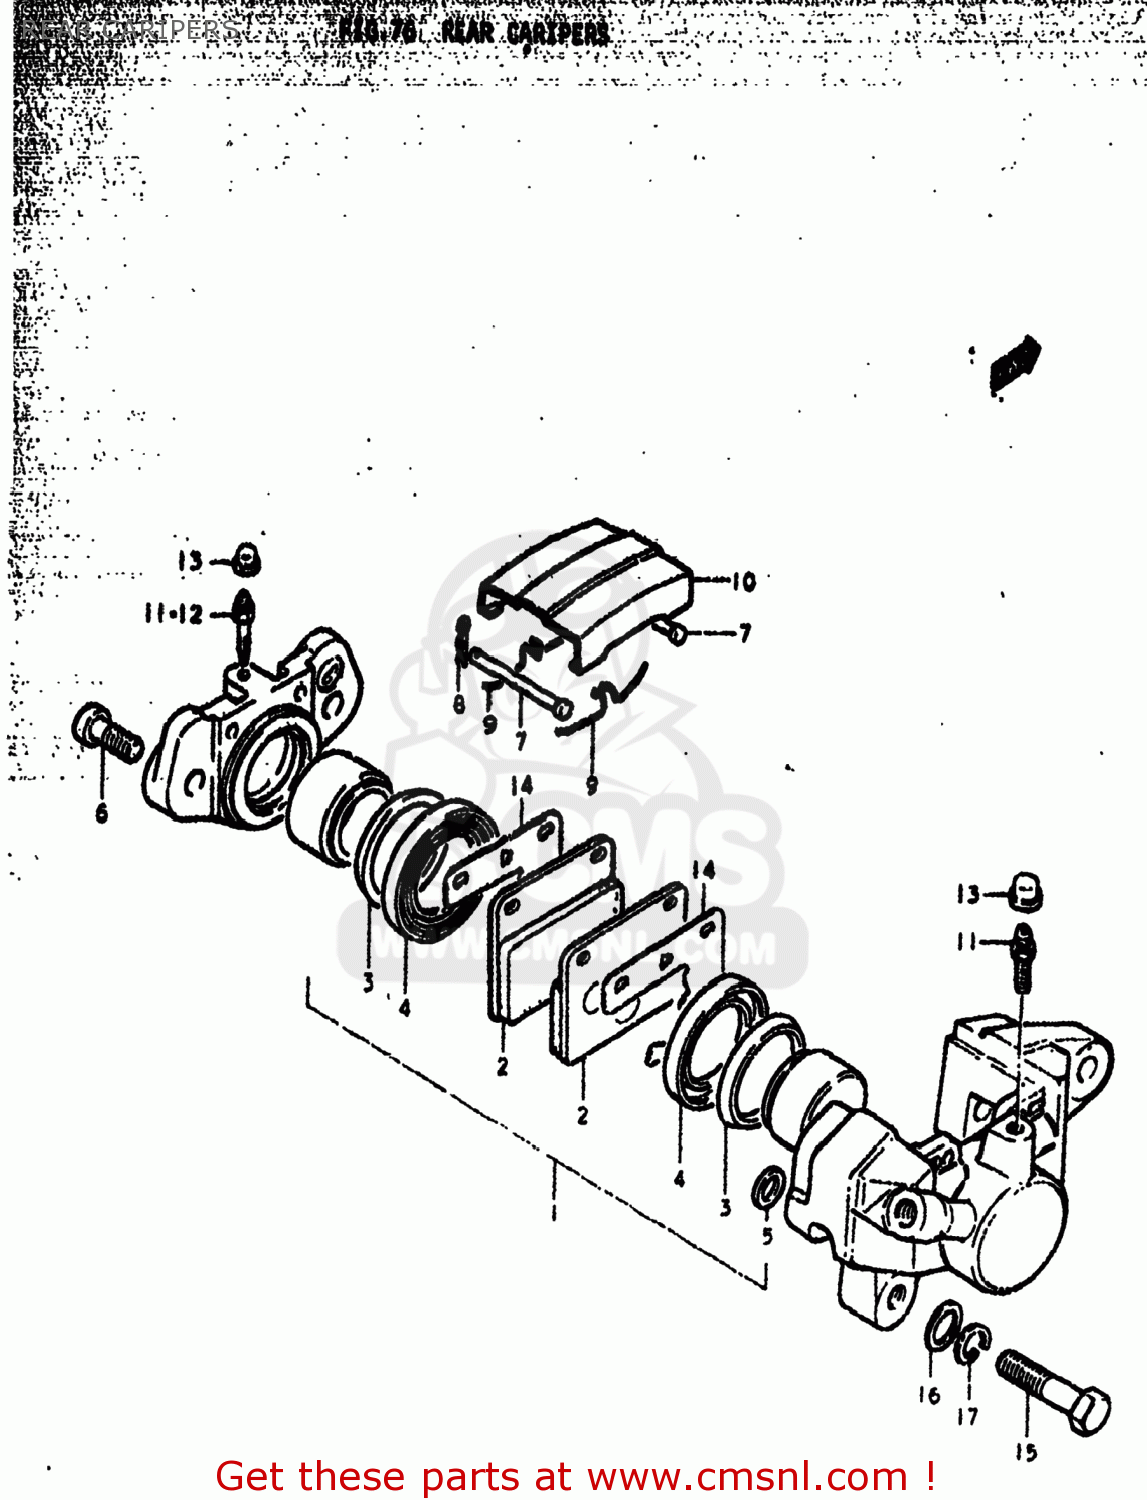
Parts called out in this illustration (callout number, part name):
0	CALIPER ASSEMBLY,REAR
1	PISTON SET
2	PAD,BRAKE
3	SEAL,PISTON
4	BOOT,PISTON
5	SEAL,PISTON
6	BOLT,HOUSING
7	PIN,PAD
8	CLIP,PAD PIN
9	SPRING
10	COVER,DUST
11	BLEEDER
12	BREATHER
13	CAP,BREATHER
14	SHIM,RR CALIPER
15	BOLT 10X34
16	WASHER
17	LOCK WASHER
